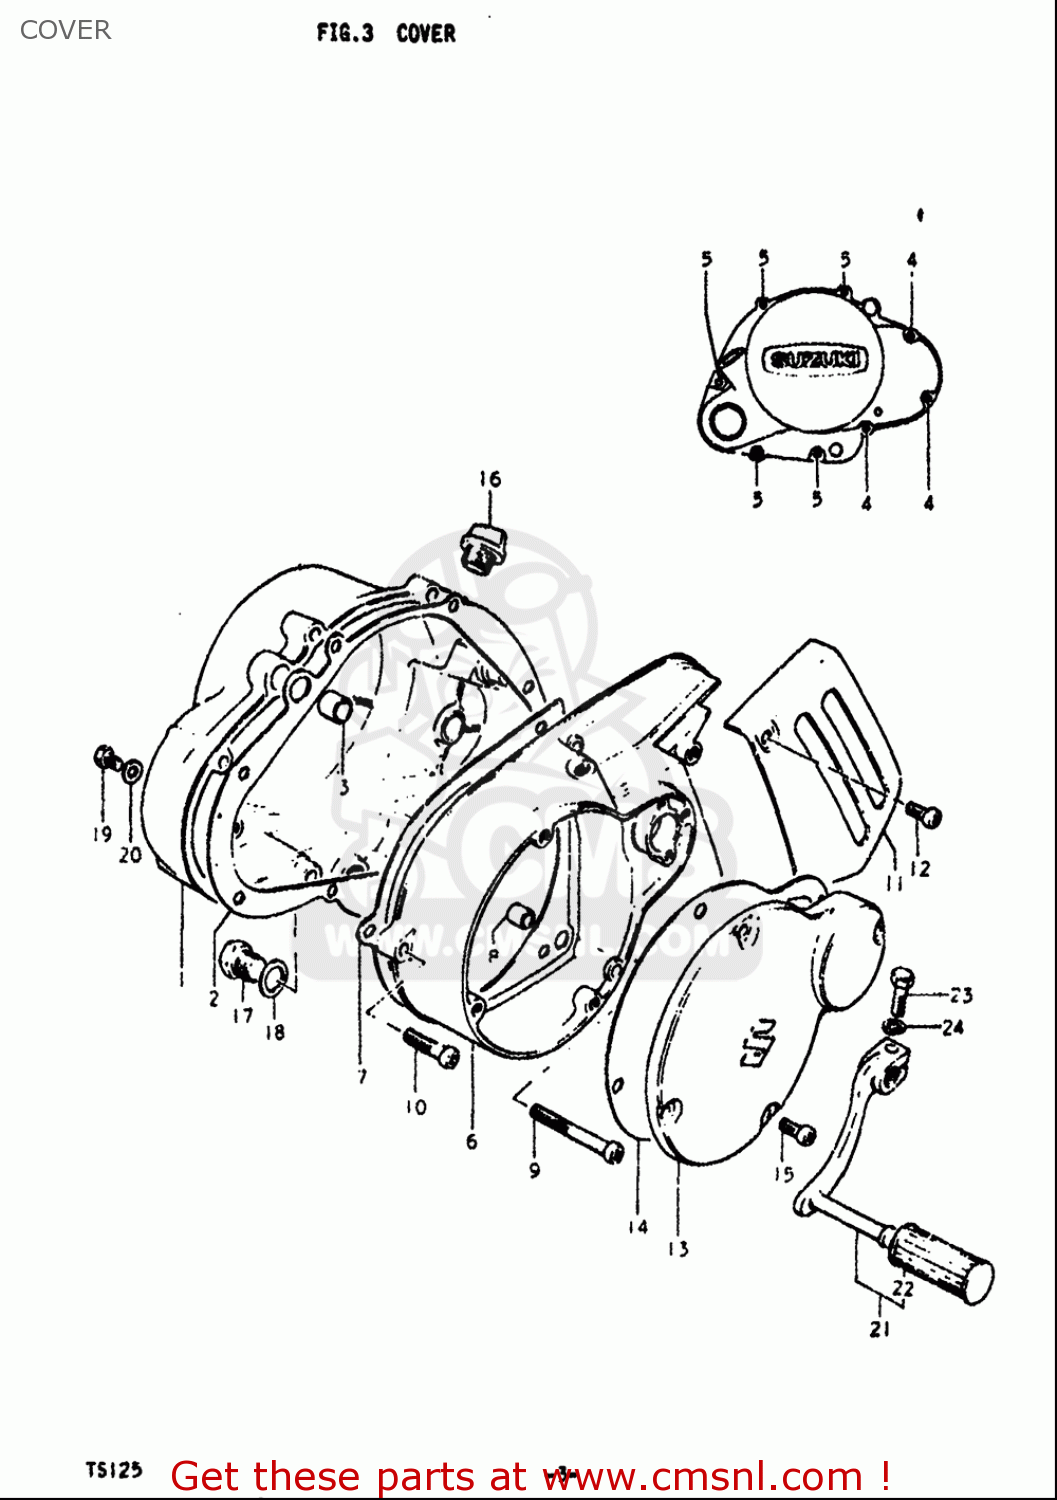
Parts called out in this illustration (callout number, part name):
2	GASKET,CLUTCH COVER (NAS)
3	PIN
4	SCREW
5	SCREW
8	PIN
9	SCREW
10	SCREW
12	SCREW
13	CAP,MAGNETO INSPECTION
14	GASKET,MAGNETO INSPECTION CAP (NAS)
15	SCREW
16	PLUG SET
17	PLUG(MAGNETO)
18	GASKET(14X19.2X2) (NAS)
19	SCREW(6X10)
20	GASKET(6.2X11X1) (NAS)
21	LEVER ASSY,GEAR SHIFT
22	RUBBER,GEAR SHIFT PEDAL
23	BOLT
24	WASHER,LOCK
